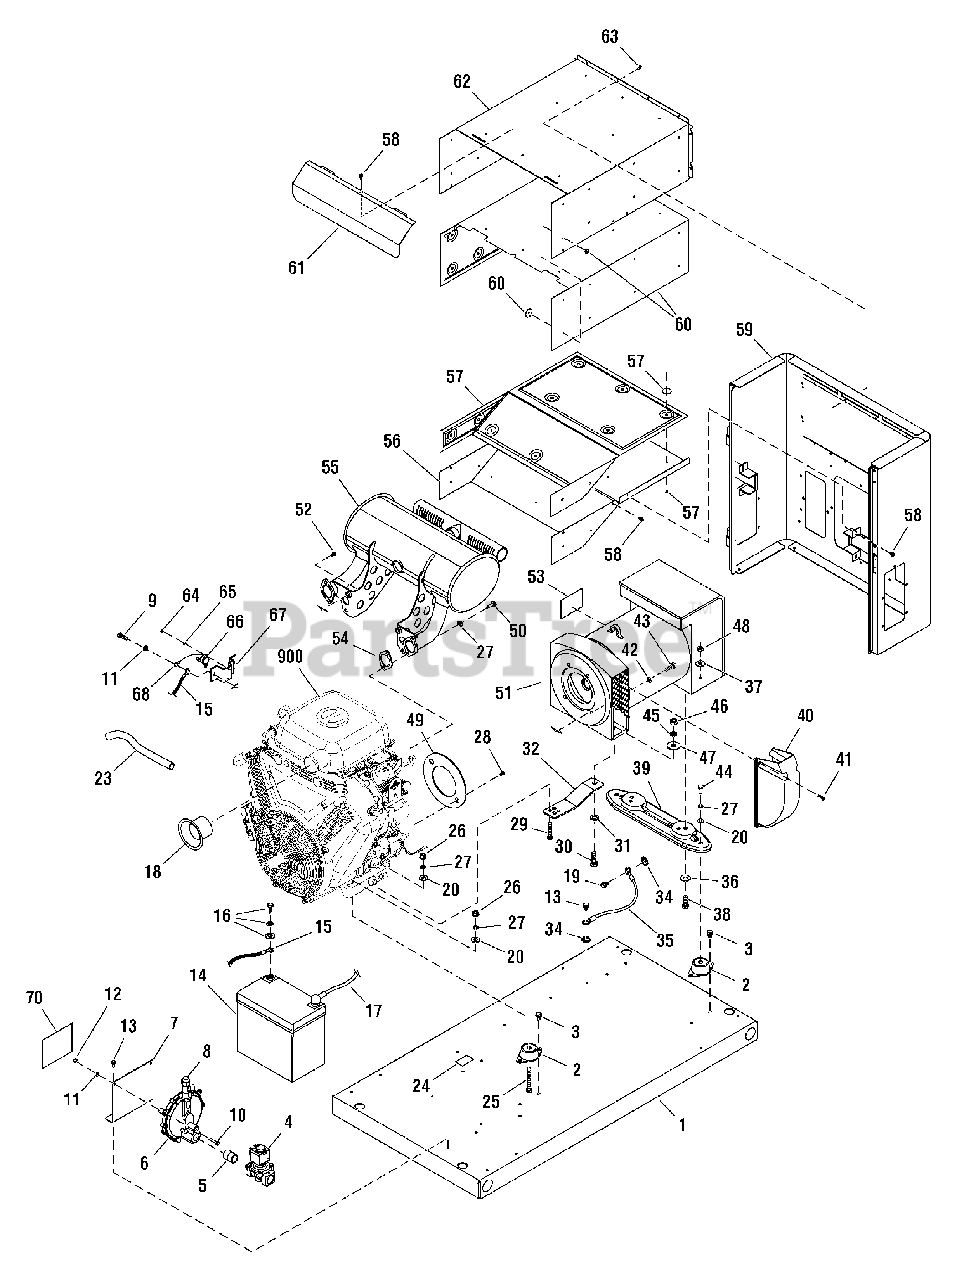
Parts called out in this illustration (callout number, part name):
2	MOUNT, Vibration
3	SCREW, Hex Head, Trilobular, 5/16-18 x 1/2
4	SOLENOID, Gas Fuel
5	FITTING, Coupling
6	REGULATOR, NG / LPG
7	BRACKET, Mounting Solenoid
9	* CAPSCREW, Hex Head, M6 - 1.0 x 16
10	* CAPSCREW, Hex Head, M6 - 1.0 x 30
11	* WASHER, Lock, 1/4
12	* NUT, M6 - 1.0
13	SCREW, Hex Head, Trilobular, 1/4 - 20 x 1/2
16	KIT, Hardware, Battery
19	* CAPSCREW, Hex Head, M6 - 1.0 x 12
20	* WASHER, Flat, 5/16 - M8
23	HOSE, Oil Drain
24	DECAL, Oil Drain
25	* CAPSCREW, Hex Head, 5/16-18 x 2-1/2
26	* NUT, 5/16-18
27	* WASHER, Lock, 5/16 - M8
28	* CAPSCREW, Hex Head, SEMS, 5/16-24 x 3/4
29	* CAPSCREW, Hex Head, 5/16-18 x 2
30	* CAPSCREW, Hex Head, M12 - 1-3/4 x 35
31	* WASHER, M12
32	SUPPORT, Alternator
34	* WASHER, Shakeproof Ext. M6-1/4
36	* WASHER, Lock, M10
37	* WASHER, Flat, M10
38	* CAPSCREW, Hex Head, M10 - 1.5 x 30
39	BRACKET, Mounting Alternator, Black
41	* SCREW, Phillips Head, M5 - 0.8 x 20
42	* WASHER, Lock, 3/8
43	* SCREW, Socket Head, 3/8-16 x 1-1/4
44	* CAPSCREW, Hex Head, 5/16-18 x 3/4
45	* WASHER, Lock, M12
46	* NUT, Hex, M12 - 1-3/4
47	* WASHER, Flat, M12
48	* NUT, M10 - 1-1/2
49	DISK, Engine Air
50	Screw
51	ALTERNATOR
53	DECAL, Caution Hot Surface
56	BASE, Muffler Box
57	KIT, Insulation, Muffler Base
58	CRIMPTITE, 10 - 24 x 1/2
59	BULKHEAD ASSEMLBY, Alternator
62	BOX, Muffler Top
63	SCREW, 10-32 x 5/8
64	* SCREW, Phillips Head, 4-40 x 0.19
65	* WASHER, Lock, #4
66	SWITCH, Oil Temp
67	PLATE, Switch Oil Temp
70	DECAL, Requirements, Fuel
900	** ENGINE
